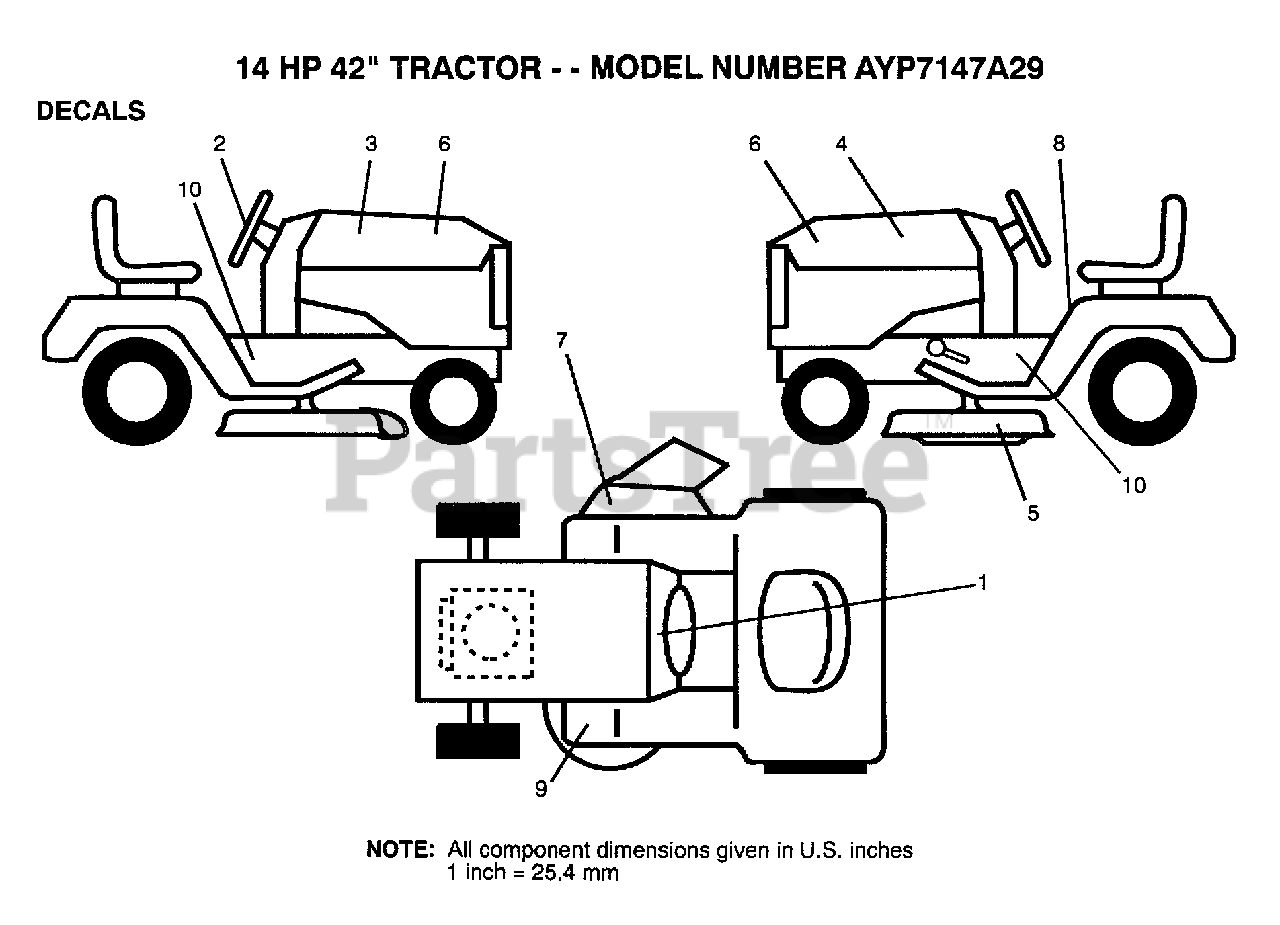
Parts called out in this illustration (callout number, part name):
5	DECAL INSTRUCTION CAUTION
7	DECAL WARING
8	DECAL
